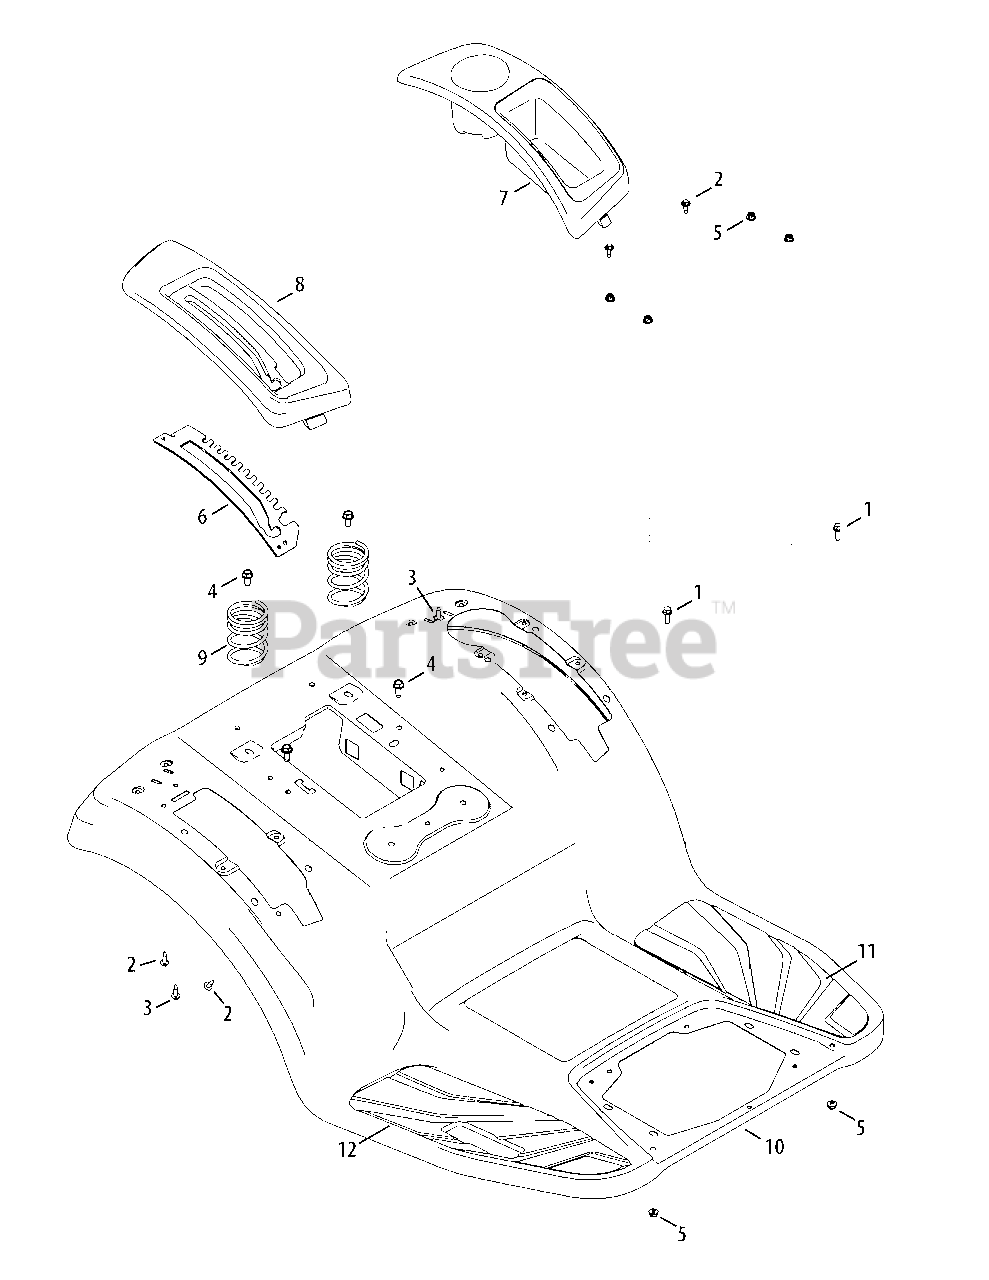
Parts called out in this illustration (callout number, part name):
1	Hex flange Screw, 1/4-20 x .75
2	Screw, M6-1 x .625
3	Screw, 1/4-10 x .75
4	Screw, Self-tapping, 3/8-16, 0.750,
5	Nut, Flange Lock, 1/4-20, Nylon
7	Cover, LH
8	Cover, RH, Electric PTO
9	Compression Spring, 2.50 x 3.951 x .207
10	Fender
11	Pad, Foot, LH
12	Pad, Foot, RH
